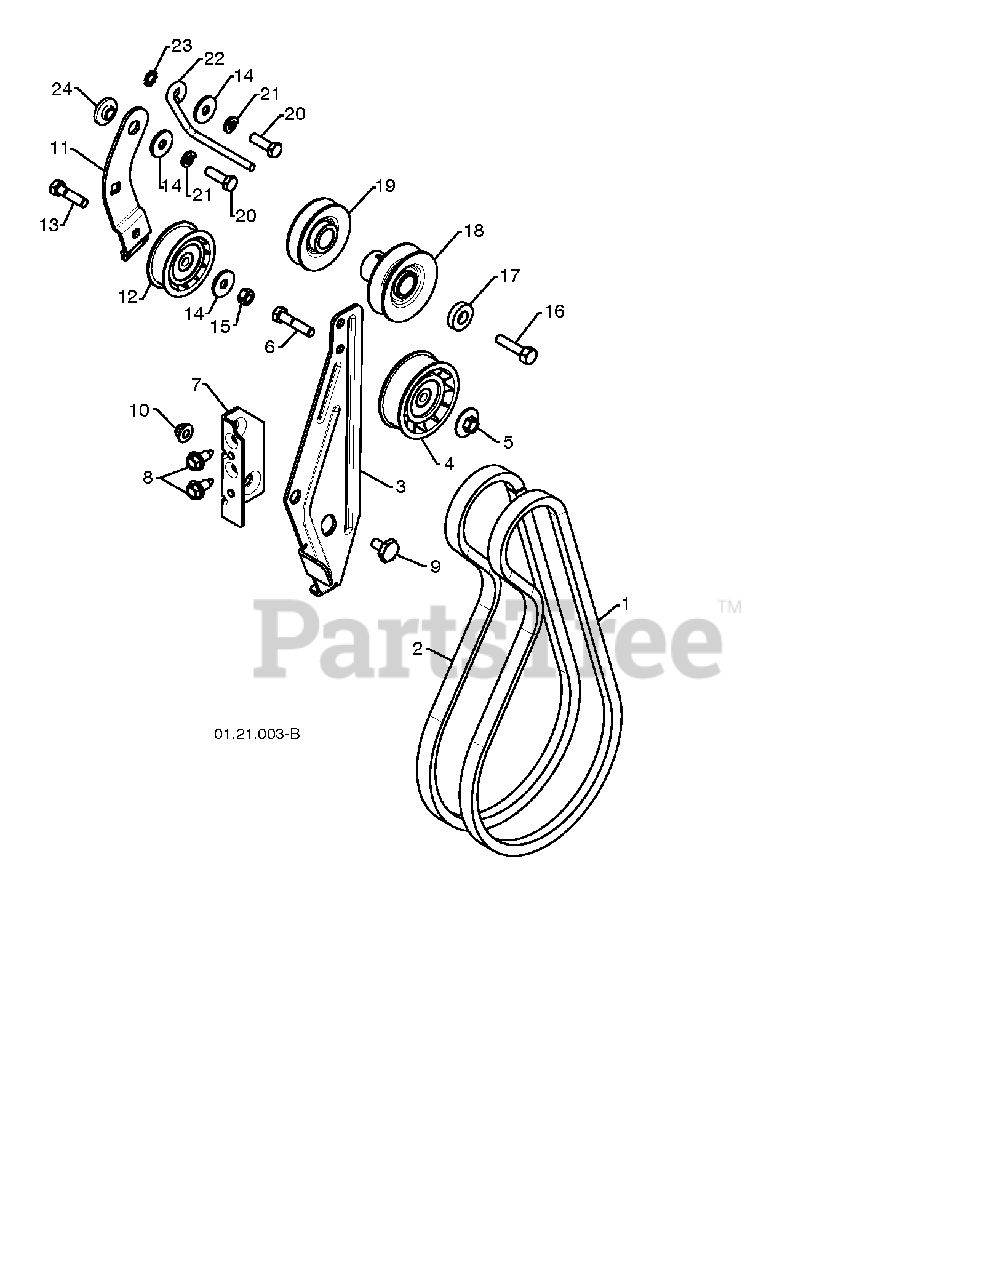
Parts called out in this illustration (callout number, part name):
1	BELT.V.IMPELLER
2	V-BELT.TRACTION
3	RP ARM.IDLER.BRAKE.
4	RP BRACKET.IDLER.PIVOT
5	PULLEY.W/SPACER.2.75
6	HEX BOLT
7	NUT.FLANGE.HEX.5/16X18.BLACK
8	NUTNYLOK.FLRANGE.5/16-18
9	BOLT.SHOULDER.1/2X12
10	BOLT.HEX.HD.WASHER.5/16-18X.75
11	ARM, IDLER
12	PULLEY.W/SPACER.2.25
13	BOLT.5/16-18X1-1/4 FULL.THREAD
14	STEEL WASHER
15	NUT.71038.31-18.HEX.NYLOCK
16	SCREW, HEX HD 3/8-24 X 1-3/8
17	WASHER, FLAT 3/8
18	PULLEY.IMPELER.
19	PULLEY.ENG.TRACTION
21	LOCKWASHER
22	GUIDE BELT
23	WASHER EXT TOOTH LOCK 5/16
24	BUSHING, IDLER PIVOT
